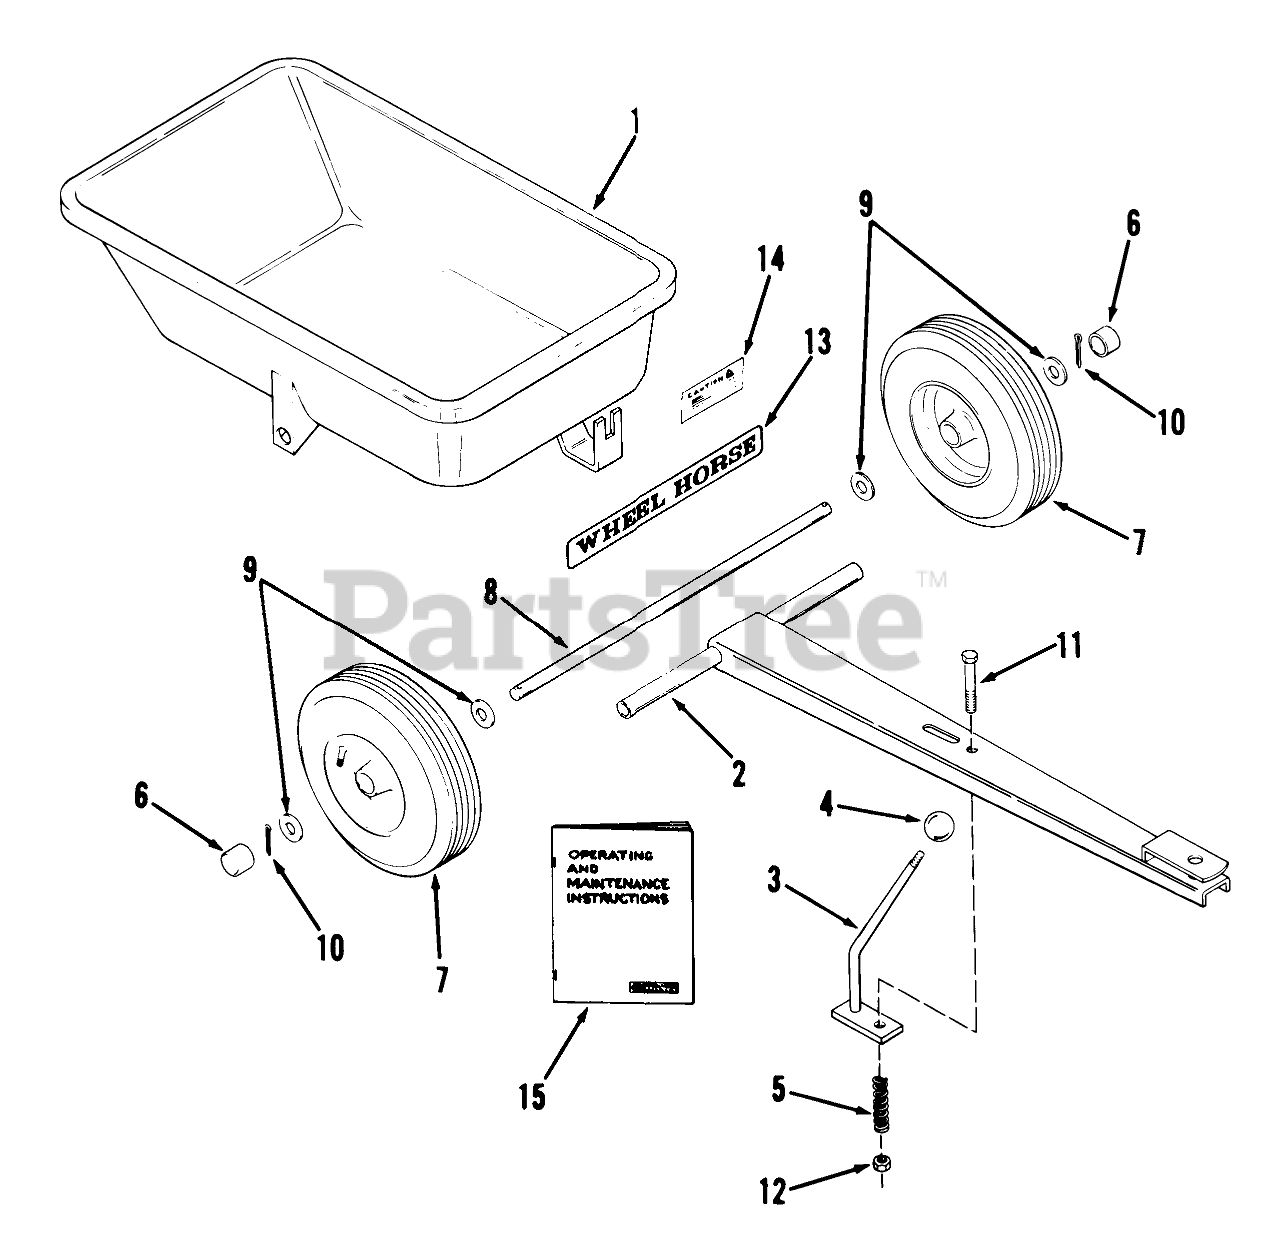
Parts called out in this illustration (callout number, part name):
1	Box Ass-y.
2	Frame Ass-y.
3	Latch Ass-y.
4	Knob
5	Spring
6	Hub Cap
7	Tire & Wheel
7	Wheel
7	Tire
7	Tube
8	Axle
9	WASHER
10	Cotter Pin
11	HHCS
12	Nut
13	DECAL-WHEEL HORSE
14	Decal-Weight Limit
15	Operating and Maintenance Instructions
